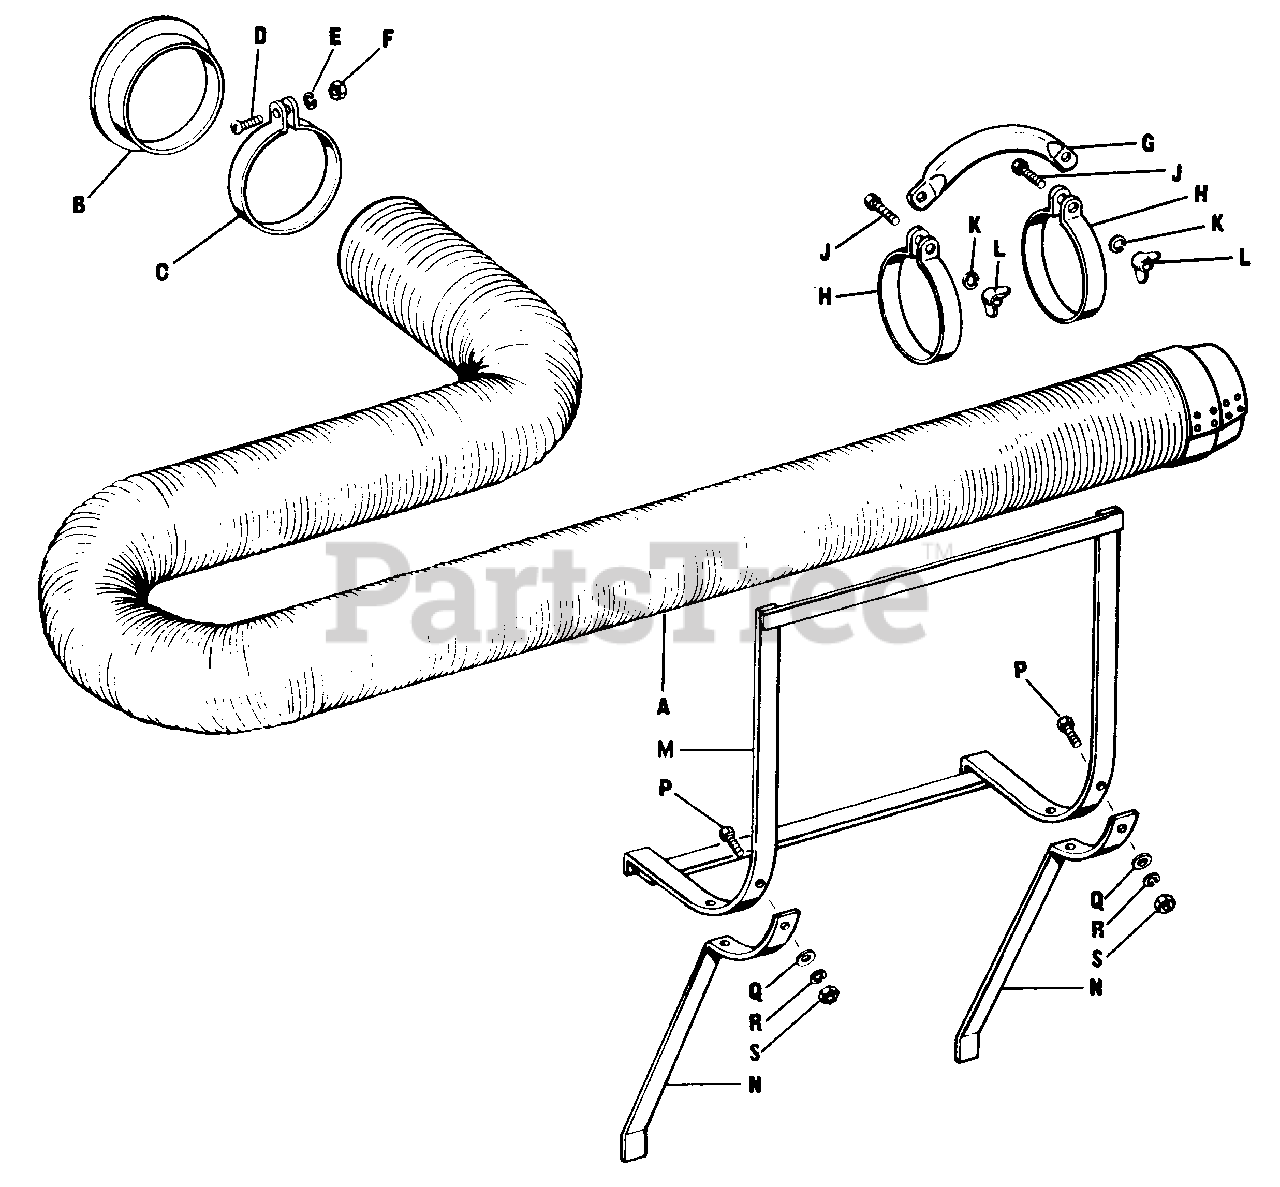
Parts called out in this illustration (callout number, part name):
A	Hose Assembly
B	Hose Flange
C	Hose Clamp
D	Rnd. Slot. Hd. Machine Screw, 1/4"-20 x 3"
E	Lock Washer 1/4"
F	Full Hex. Nut, 1/4"-20
G	Hose Handle
H	Hose Clamp Handle
J	Hex. Cap Screw, 5/16"-18 x 3/4"
K	Lock Washer, 5/16"
L	Wing Nut, 5/16"-18
M	Hose Carrier Assembly
N	Carrier Support
P	Hex. Cap Screw 5/16"-18 x 7/8"
Q	Plain Washer 5/16"
R	Lock Washer 5/16"
S	Full Hex. Nut 5/16"-18
